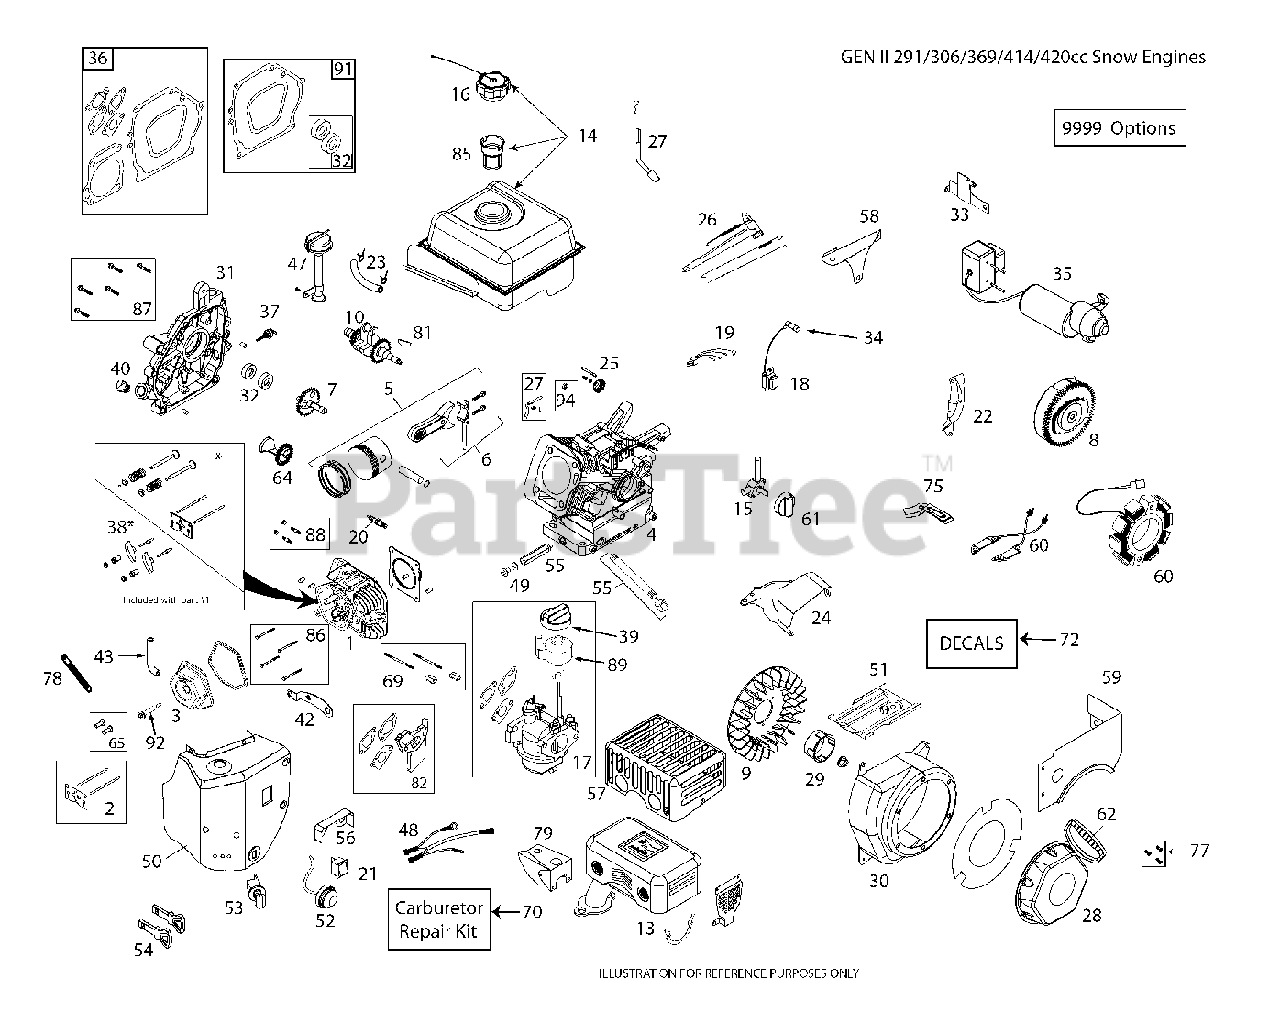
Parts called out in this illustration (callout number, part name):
1	CYL.HEAD.ASSY.45 DEG.NON-GEN
2	PUSH ROD TAPPET KIT
3	VALVE.COVER.LCT.414CC.
4	CYLINDER ASSY
5	PISTON.AND.ROD.ASSY(SK4141400)
6	CONNECTING ROD ASSEMBLY
7	CAMSHAFT(SK4141600)
8	FLYWHEEL.EL.ST.SKSN4408.1
9	FLYWHEEL.FAN(SK4144000)
10	CRANKSHAFT KEYED #18 LCT 414C
13	MUFFLER ASSY LCT SNO
14	FUEL.TANK.ASSY.SNOW(SKSN4300)
15	FUEL.PETCOCK.SNOW(SKSN4900)
16	FUEL.TANK.CAP.SNOW(SKSN4301)
17	CARBURETTOR 414 W/IDLEDOWN
18	IGNITION.COIL.(CDI).291-414CC
19	Husqvarna TBD
20	SPARK.PLUG(SK2911550)
21	Husqvarna TBD
22	Husqvarna TBD
23	FUEL HOSE KIT
24	RP TOP SHIELD
25	GOVERNOR.GEAR.ASSY(SK4142900)
26	GOVERNOR.ARM.ASSY(SKSN4502)
27	GOVERNOR.SHAFT(SK4143100)
28	RECOIL.START.ASSY.SNW(SKSN4600
29	STARTER.CUP.SML.SNOW(SKSN4601)
30	BLOWER HOUSING.LCT 369 GLOSS
31	CRANKCASE.COVER.LCT.414CC.HIGH
32	OIL SEAL KIT NON-GENERATOR
33	ELECTRIC.START.BRKT(SKSN4405)
34	SPARK.PLUG.BOOT.SNW,SKSN4691.1
35	ELEC.START.ASSY.SNOW(SKSN4400)
36	KIT.ENGINE GASKET.LCT.414CC
37	DIPSTK.OIL.BLK.LCTSK4143711.1
38	ROCKER ARM KIT
39	CHOKE.KNOW.SNOW(SKSN4500)
40	NONREMVABLE.OIL.PLUG(SK4143715
42	Husqvarna TBD
43	TUBE.BREATHER.LCT.219CC/414CC
47	HIGHOIL.FILL.ASSY.KIT(SKSN4911
48	WIRE.HARNESS(SKSN4406)
49	OIL.DRAIN.PLUG
50	HEATER.BOX.ASSY-SNW(SKSN4100)
51	SHIELD.CYLINDER.SNOW(SK4141010
52	PRIMER.BULB.ASSY(SKSN4304)
53	KEY.SWITCH.ASSY.SNOW(SKSN4401)
54	KEY SET(2 KEYS) SKSN0407.1
55	OIL PIPE DRAIN EXTENDED.LCT SK
56	SHIELD.VAPOR(SKSN4606)
57	Husqvarna TBD
58	PLATE.GOVERN.LINK.S
59	SKIRT FUEL TANK
60	ALTERN.60WATT.SKSN2402.1
61	FUEL KNOB-SNOW
62	HANDLE.RECOIL.DELUXE.LCT
64	COUNTER WEIGHT KIT
65	TAPPET KIT.LCT.SK2911005.1
69	STUD.CARB.MOUTING.KIT.414CC
70	CARBURETTOR REPAIR KIT 291CC/4
72	Husqvarna TBD
74	MUFFLER SHIELD
75	SHIELD.U/FYWHL.CHARG(SKSN4604)
77	BOLT.KIT.RECOIL.LCT.ALL.ENGINE
78	STRAP.RETAINING.TUBE.BREATHER.
79	SHIELD CARBURRETOR COVER 414
81	KEYS.FLYWHEEL.208/414CC.5PACK
82	SPACER.CARBURETOR.414CC.LCT
85	STRAINER.FUEL.TANK.LCT.208CC
86	KIT.BOLT.CYLINDER.HEAD.(4PC)
87	KIT.BOLT.CRANKCASE.COVER.414CC
88	STUD.MUFFLER.KIT.LCT
89	KNOB LCT.SKSN5325.1 SPEED
91	GASKET KIT CRANKSHAFT.LCT
92	CENTER VALVE COVER BOLT
94	SEAL GOVERNOR SHAFT OIL.LCT
9999	HIGH ALTITUDE JET 6000FT
